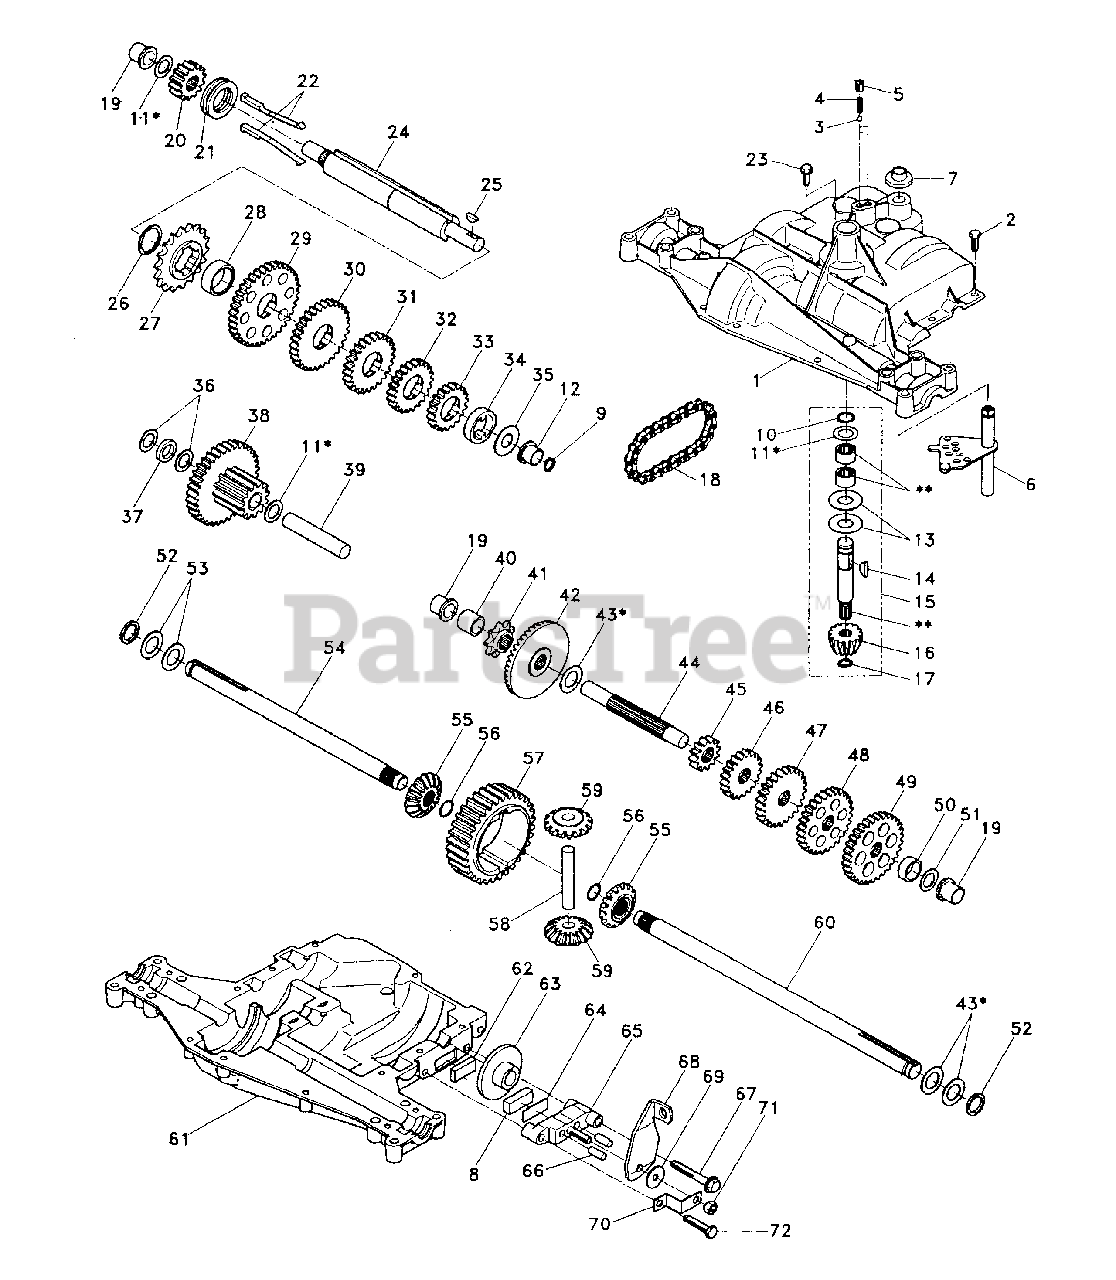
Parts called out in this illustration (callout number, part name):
1	Housing, Upper
2	Screw, Self-Tapping, Large 1/4-20 x .734
3	Ball, Detent
4	Spring, Detent
5	Screw, Set
6	Kit, Shifter Assembly
7	Boot, Shifter
8	Puck, Friction
9	Square Ring
10	Ring, Retaining
11	Assembly, Kit, Shim .625 Shaft
12	Bearing, Flange
13	Washer, Plain .632 x 1.38 x .046
14	Key, Woodruff, #9
15	Assembly, Kit, Input Shaft
16	Pinion, Bevel, 14 Teeth
17	Ring, Retaining
18	Chain, 24 Pitches
19	Bearing, Flange
20	Gear, Spur, 14 Teeth
21	Collar, Clutch
22	Assembly, Kit, Clutch Keys
23	Screw, Self-Tapping, with Sealer
24	Shaft, Intermediate
25	Key, Woodruff, #61
26	Ring, Retaining
27	Sprocket, 18 Teeth
28	Spacer
29	Gear, Spur, 37 Teeth
30	Gear, Spur, 30 Teeth
31	Gear, Spur, 25 Teeth
32	Gear, Spur, 22 Teeth
33	Gear, Spur, 19 Teeth
34	Spacer 1.133 x 1.50 x .375
35	Washer, Plain .640 x 1.37 x .061
36	Washer, Plain .632 x 1.00 x .026
37	Spacer .630 x 1.00 x .169
38	Assembly, Gear, Combination of 12 Teeth and 35 Teeth
39	Shaft, Idler
40	Spacer .635 x .875 x .755
41	Sprocket 9 Teeth
42	Gear, Bevel, 42 Teeth
43	Assembly, Kit, Shim, .750 Shaft
44	Shaft, Drive
45	Gear, Spur, 12 Teeth
46	Gear, Spur, 20 Teeth
47	Gear, Spur, 25 Teeth
48	Gear, Spur, 28 Teeth
49	Gear, Spur, 31 Teeth
50	Spacer .781 x 1.00 x .375
51	Washer, Plain .632 x 1.00 x .060
52	Washer, Neoprene
53	Washer, Plain .758 x 1.25 x .031
54	Axle, L.H.
55	Gear, Miter, 15 Teeth
56	Ring, Retaining
57	Gear, Spur, 32 Teeth
58	Shaft, Cross
59	Gear, Miter, 15 Teeth
60	Axle, R.H.
61	Housing, Lower
62	Puck, Friction
63	Disc, Brake
65	Jaw, Brake
66	Pin, Dowel
67	Screw, Self-Tapping 5/16-18 x 2.25
68	Lever, Actuating
69	Washer, Plain .321 x 1.00 x .055
70	Bracket, Anti-Rotation
71	Locknut 5/16-24
72	Screw, Self-Tapping 5/16-18 x 1.44
